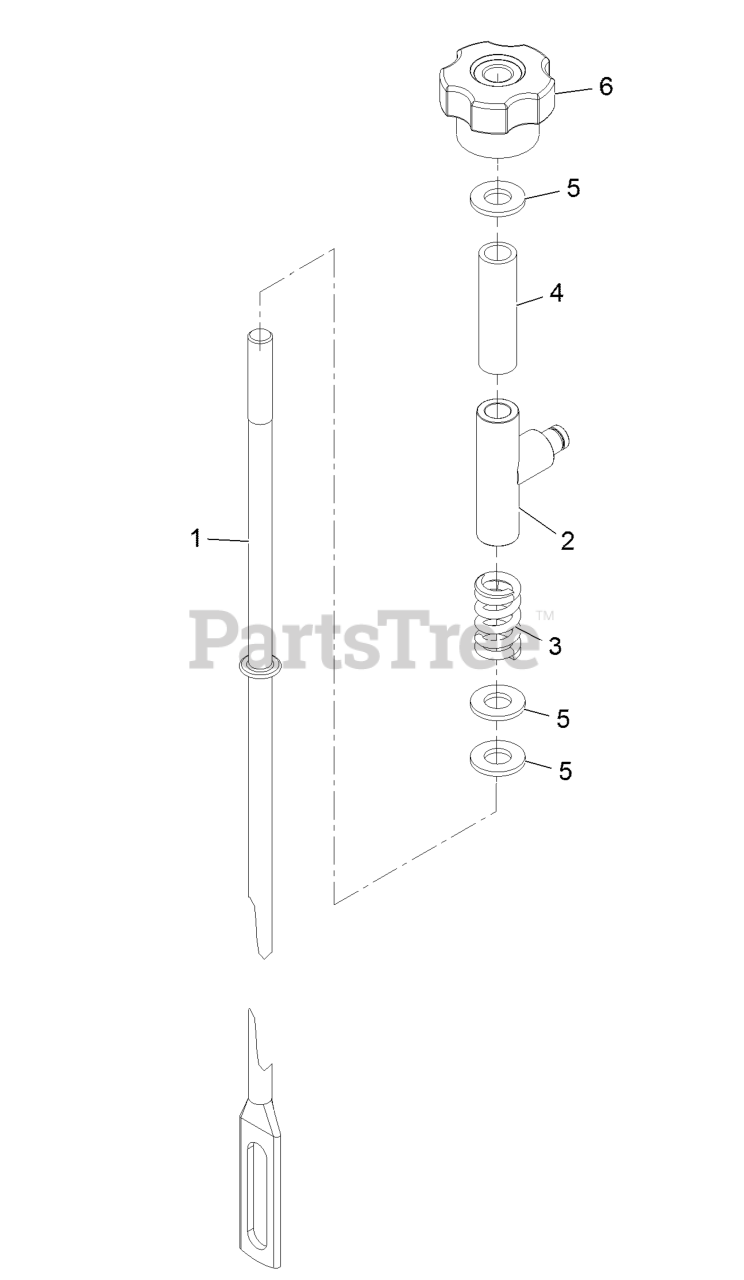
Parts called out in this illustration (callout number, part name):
1	ROD, RIGHT
3	SPRING, COMPRESSION
5	WASHER-FLAT
